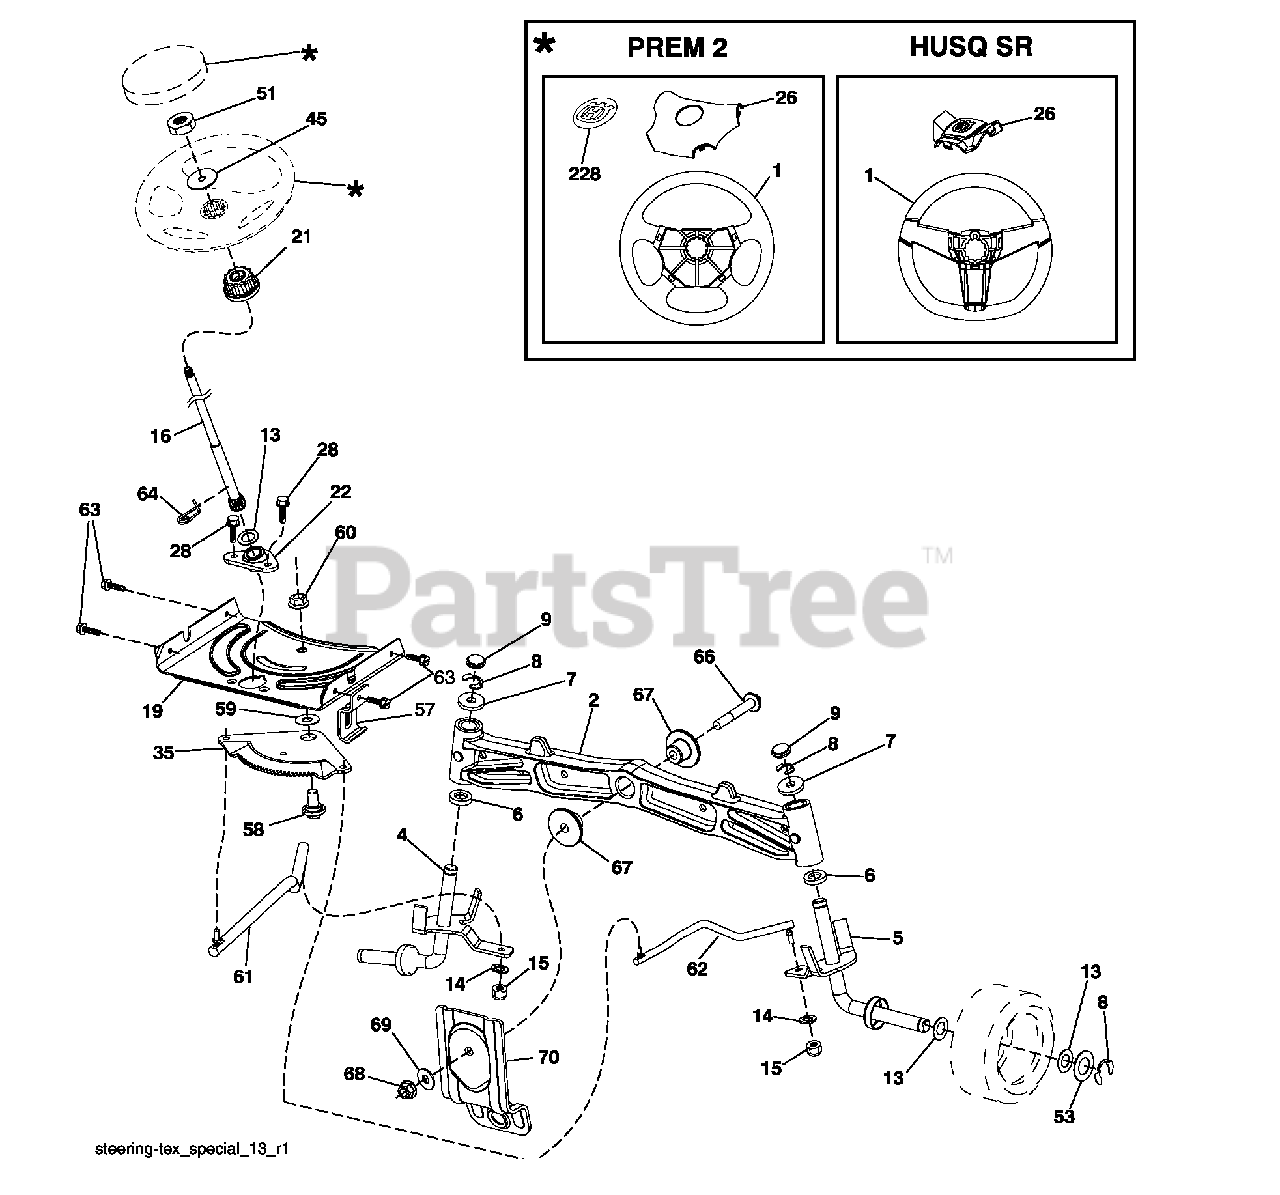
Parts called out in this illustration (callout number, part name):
1	Wheel, Steering
2	Axle Asm., Front
4	Spindle Asm., LH
5	Spindle Asm., RH
6	Washer Thrust .75 x 1.230
7	Washer 25/32 x 1-5/8 x 16 Ga.
8	Ring, Clip #T5304-75
9	Cap, Spindle
13	Washer 25/32 x 1-1/4 x 16 Ga.
14	Washer, Lock Hvy Hlcl Spr 3/8
15	Nut, Crown Lock 3/8-24 unf
16	Shaft Steering
19	Plate Steering
21	Adapter, Wheel Steering
22	Bushing, Strg. Blk
26	Insert, Wheel Steering
28	Screw 3/8-16 x 3/4
35	Gear, Sector Plate
45	Washer 9/16 ID x 2-3/8 OD 12 Ga.
51	Nut Hex Jam Toplock 1/2-20 unf
53	Washer Hardened .793 x 1.637 x .060
57	Bracket Upstop
58	Bolt Shoulder Sector Pivot CFM
59	Washer Thrust Sector Steering
60	Nut Flange Lock 5/8-11
61	Draglink LH
62	Draglink, RH
63	Screw 5/16-18 x 3/4
64	Retainer Clip Spring Steering
66	Bolt Hex Fghd 7/16-14 x 3 Serr
67	Bushing PM Front Axle
68	Nut Lock Flange 7/16-14 Gr. 5
69	Washer 1.5 x .505 x .118
70	Bracket Deck Susp. Front
